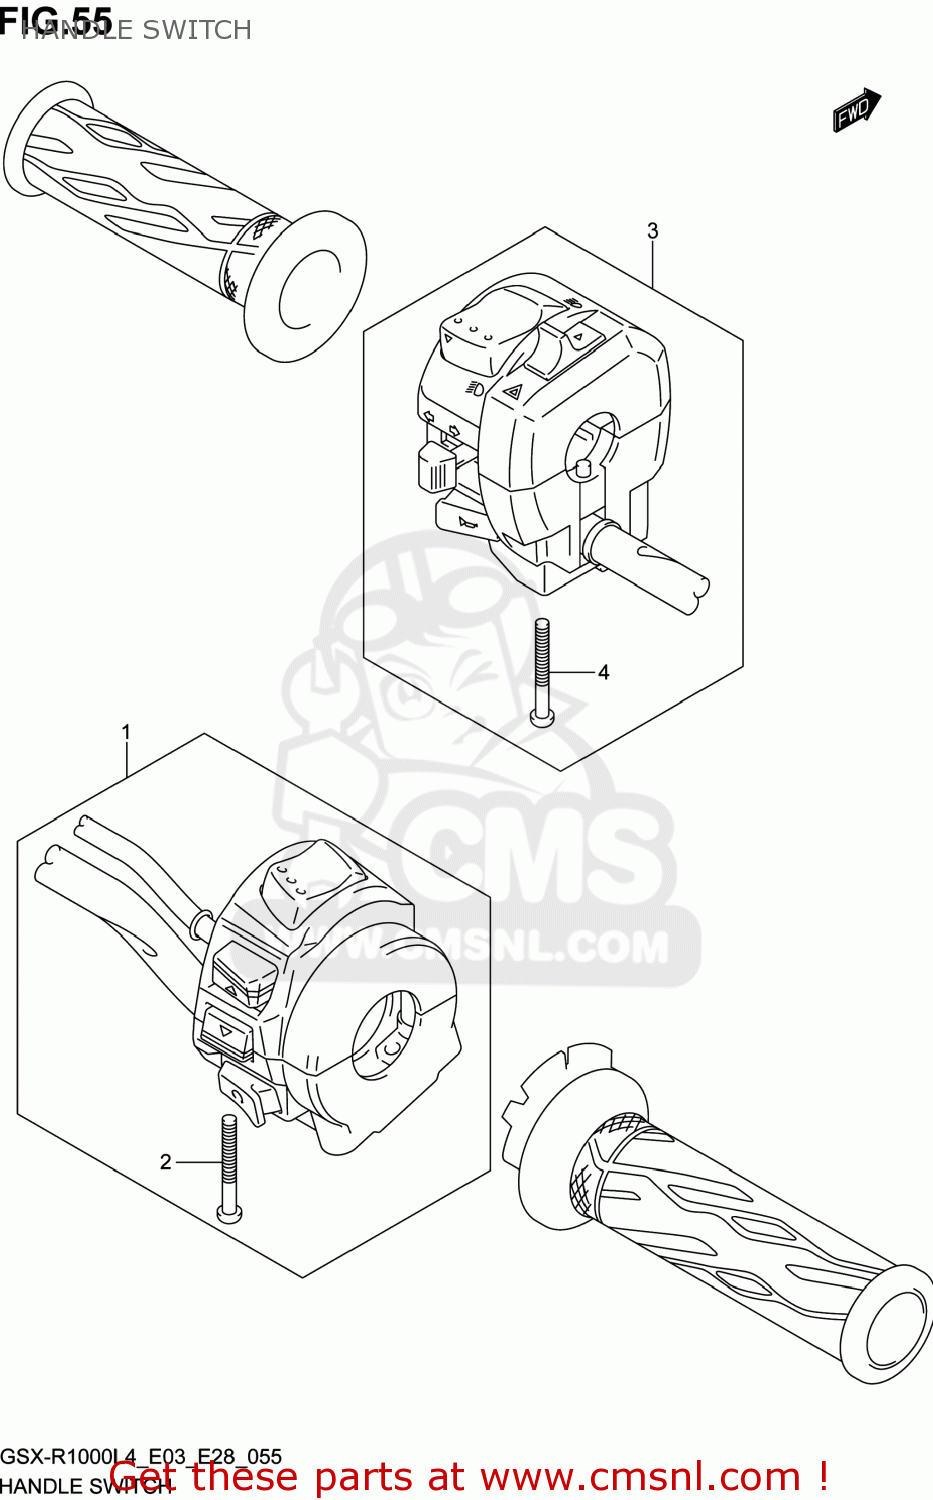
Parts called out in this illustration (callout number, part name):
1	SWITCH ASSY,HANDLE,R
2	SCREW
3	SWITCH ASSY,HANDLE,L
4	SCREW
